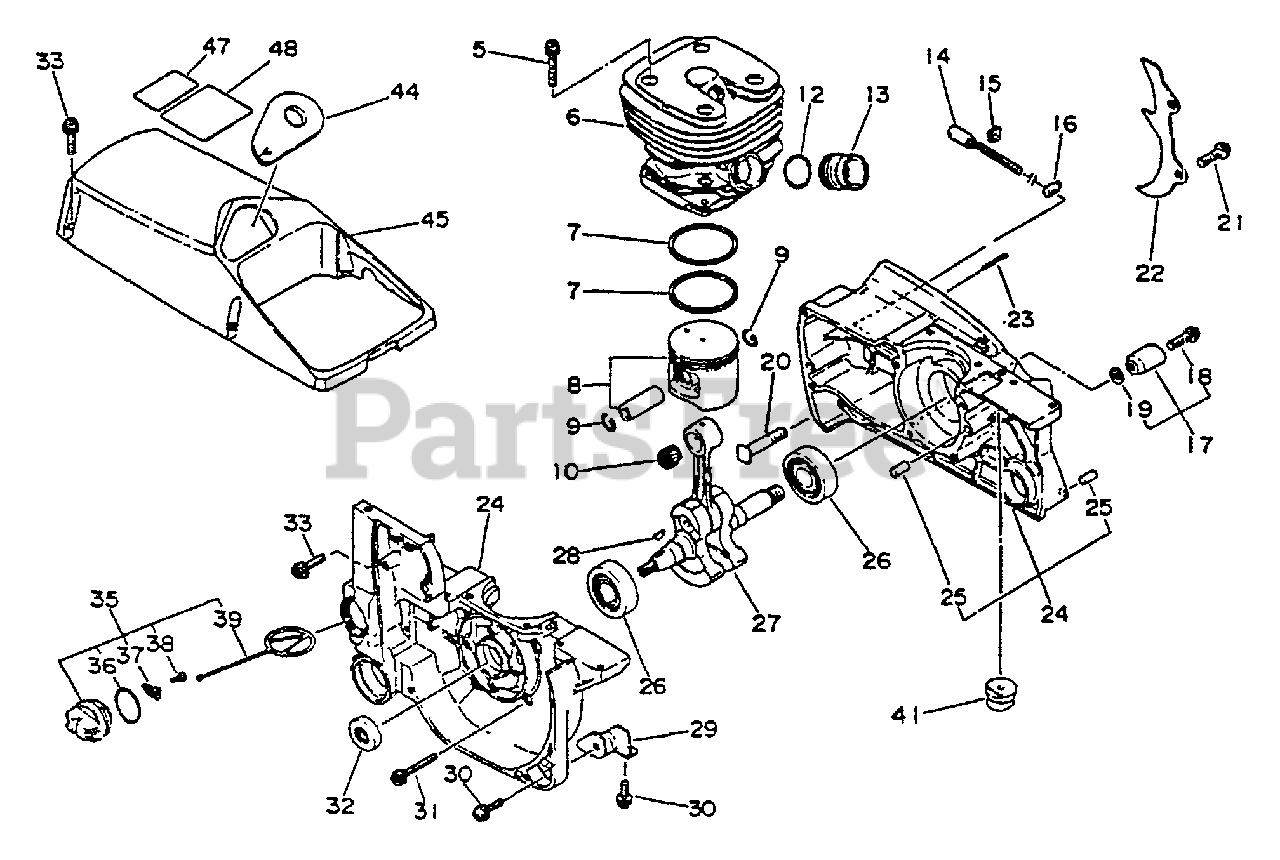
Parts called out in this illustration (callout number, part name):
5	SCREW - 6X25
6	CYLINDER
7	RING, PISTON
8	PISTON KIT
9	RING, RETAINING
10	BEARING, NEEDLE
13	ADAPTOR, INTAKE
14	SCREW, TENSIONER
16	TENSIONER, CHAIN
17	CHAIN CATCHER KIT
18	SCREW - 5X20
19	WASHER - 5
20	STUD, GUIDE BAR
21	SCREW - 6X20
23	PIN, SPLIT - 2X16
24	CRANKCASE KIT
25	PIN - LOCATING
26	BEARING SET
27	CRANKSHAFT ASSY
30	SCREW - 5X14
31	SCREW - 5X35
32	SEAL, OIL
33	SCREW - 5X20
35	CAP ASSY
37	RETAINER
38	SCREW - 3X8
39	CONNECTOR, CAP
44	PLATE, GUIDE
45	ENGINE COVER KIT - ORANGE
47	LABEL - KICK BACK
48	LABEL - CAUTION
